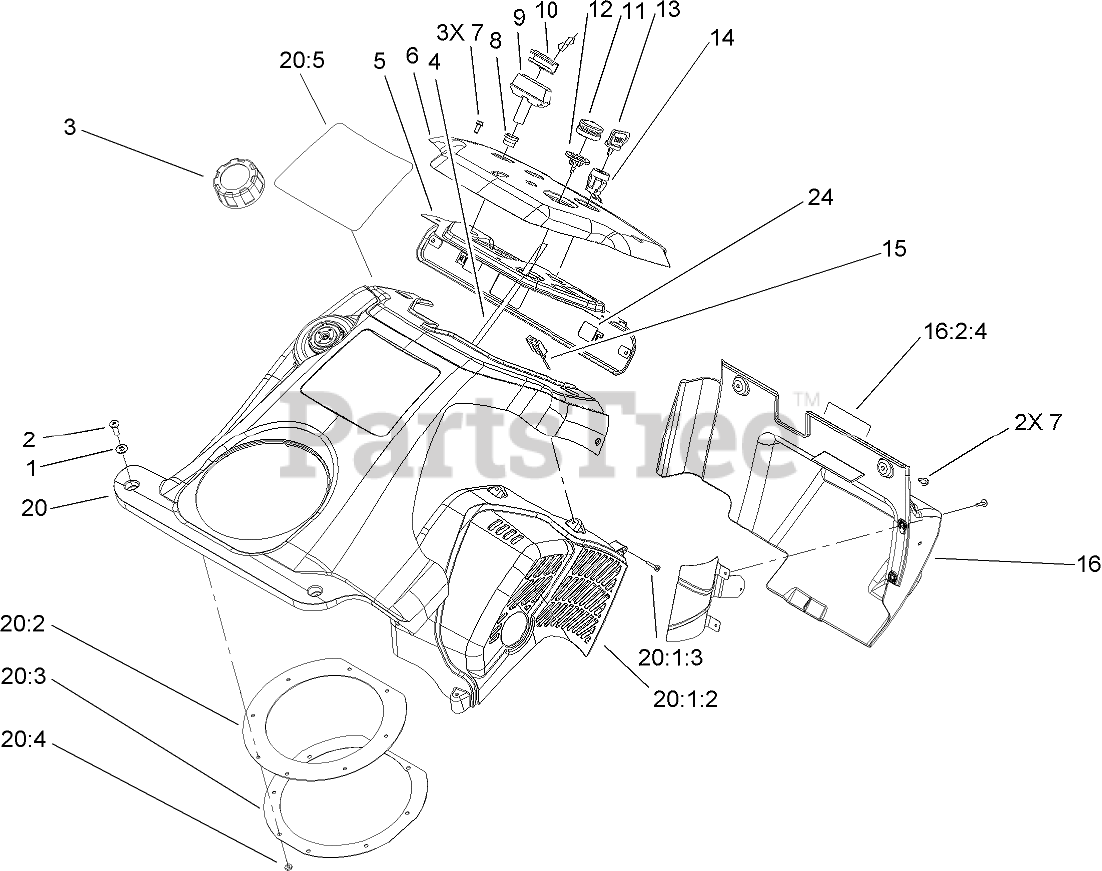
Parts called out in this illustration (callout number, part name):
1	WASHER-FLAT
2	SCREW-PPH
3	GAS CAP ASM
4	HOSE-PRIMER
5	PANEL-SUPPORT, CONTROL
6	PANEL-CONTROL
7	SCREW-HWH
8	GUIDE-ROPE, STARTER
9	HANDLE-START
10	CLIP-STARTER
11	BULB-PRIMER
12	BODY-PRIMER
13	KEY-IGNITION
14	SWITCH
15	CONNECTOR-BODY
16	LOWER SHROUD/BAFFLE W/DECAL ASM
16:2:4	DECAL
20	Upper Shroud ASM, Es 3650
20:1:2	Shield-Heat
20:1:3	SCREW-PPH
20:2	Seal-Chute
20:3	RETAINER-SEAL, CHUTE
20:4	PALNUT
20:5	DECAL - UPPER SHROUD (CCR 3650 ES)
24	NUT-SPEED
